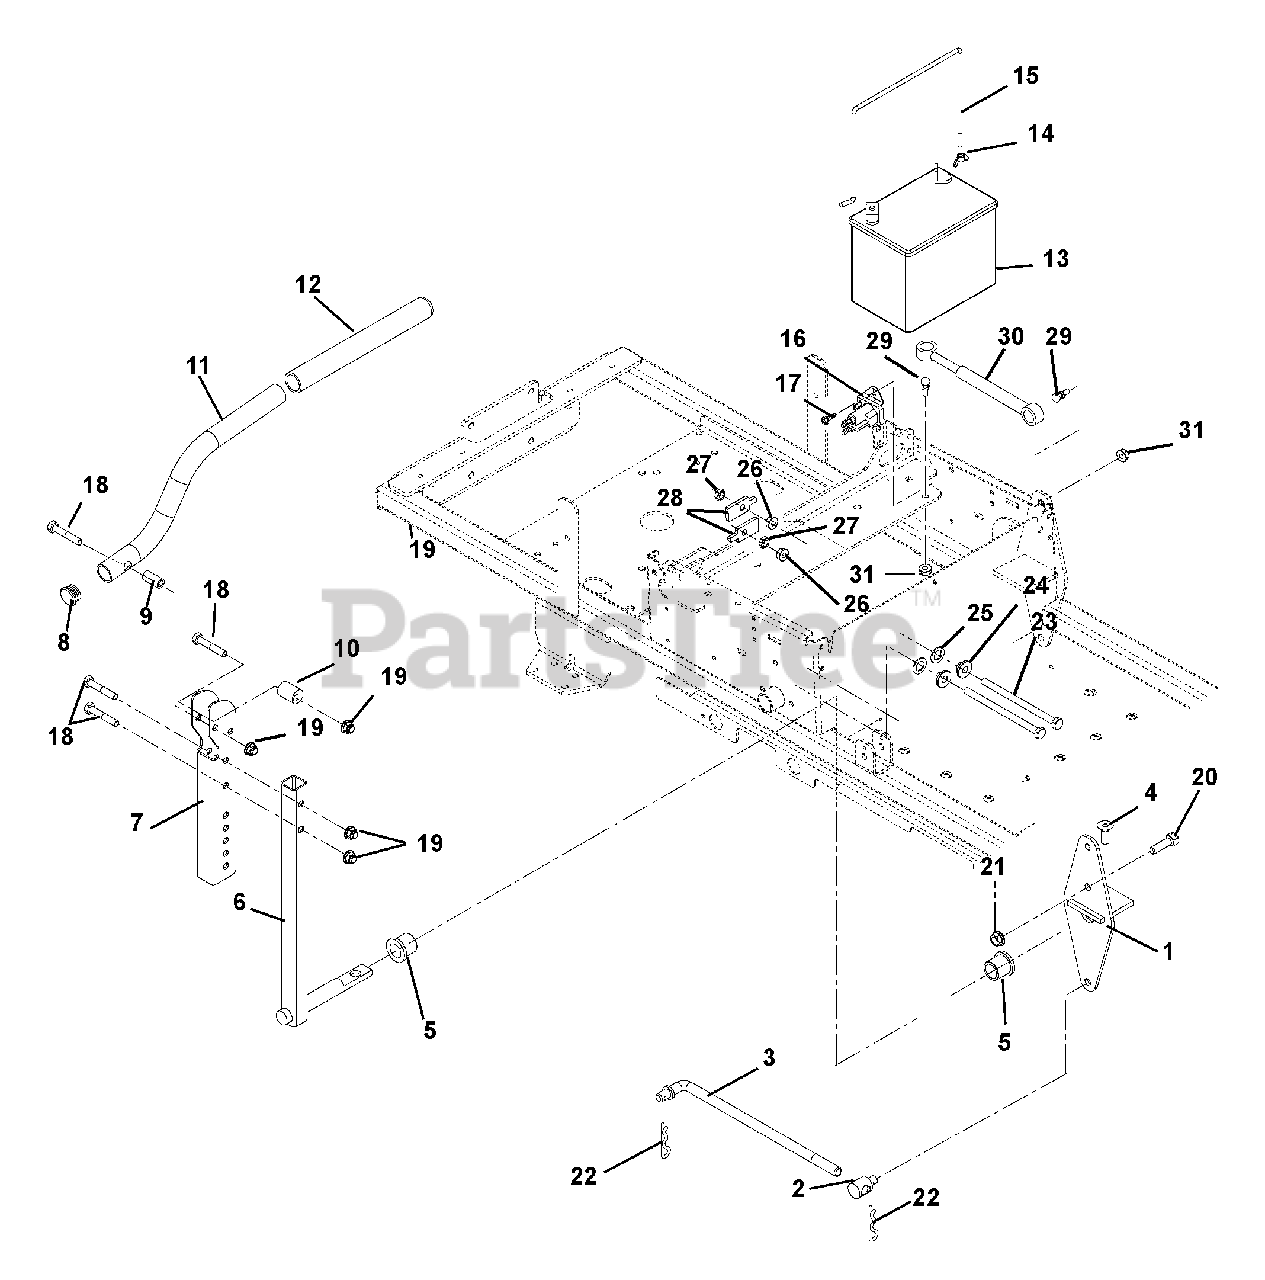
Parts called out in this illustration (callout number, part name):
1	Weldment, Control Link
2	Pivot, Rod
3	Link, Wireform
4	Bolt, .38-16 x 1 FSHCS Plain
5	Bushing, 1.00 x .75 x 1.00
6	Weldment, Control Arm
7	Channel, Upper Handlebar
8	Caplug, Handlebar
10	Eccentric
11	Handlebar
12	Grip, Handlebar
14	Nut, Lock Wing .250-20
15	Battery Rod
16	Solenoid
17	Screw, Tap .250-20 x .37
18	Bolt, Hex .31-18 x 1.75 Grade 5
19	Nut, 5/16-18 Flange Nyloc
20	Bolt, Hex .38-16 x 1.25 Grade 5
21	Nut, Hex Jam .375-16
22	Pin, Hair Internal .08 x .18 x 1.18
23	Bolt, Hex 5/16-18 x 5 Grade 2
24	Bushing, Flange .312 x .500 x .344 x .880
25	Washer, Flat Steel .52 x .827 x .062
26	Nut, Spin Lock-Flange .312-18
27	Nut, Jam .312-18
28	Stop Tab
29	Stud, Ball
30	Damper, Control
31	Nut, Locking Top Flange .31-18
